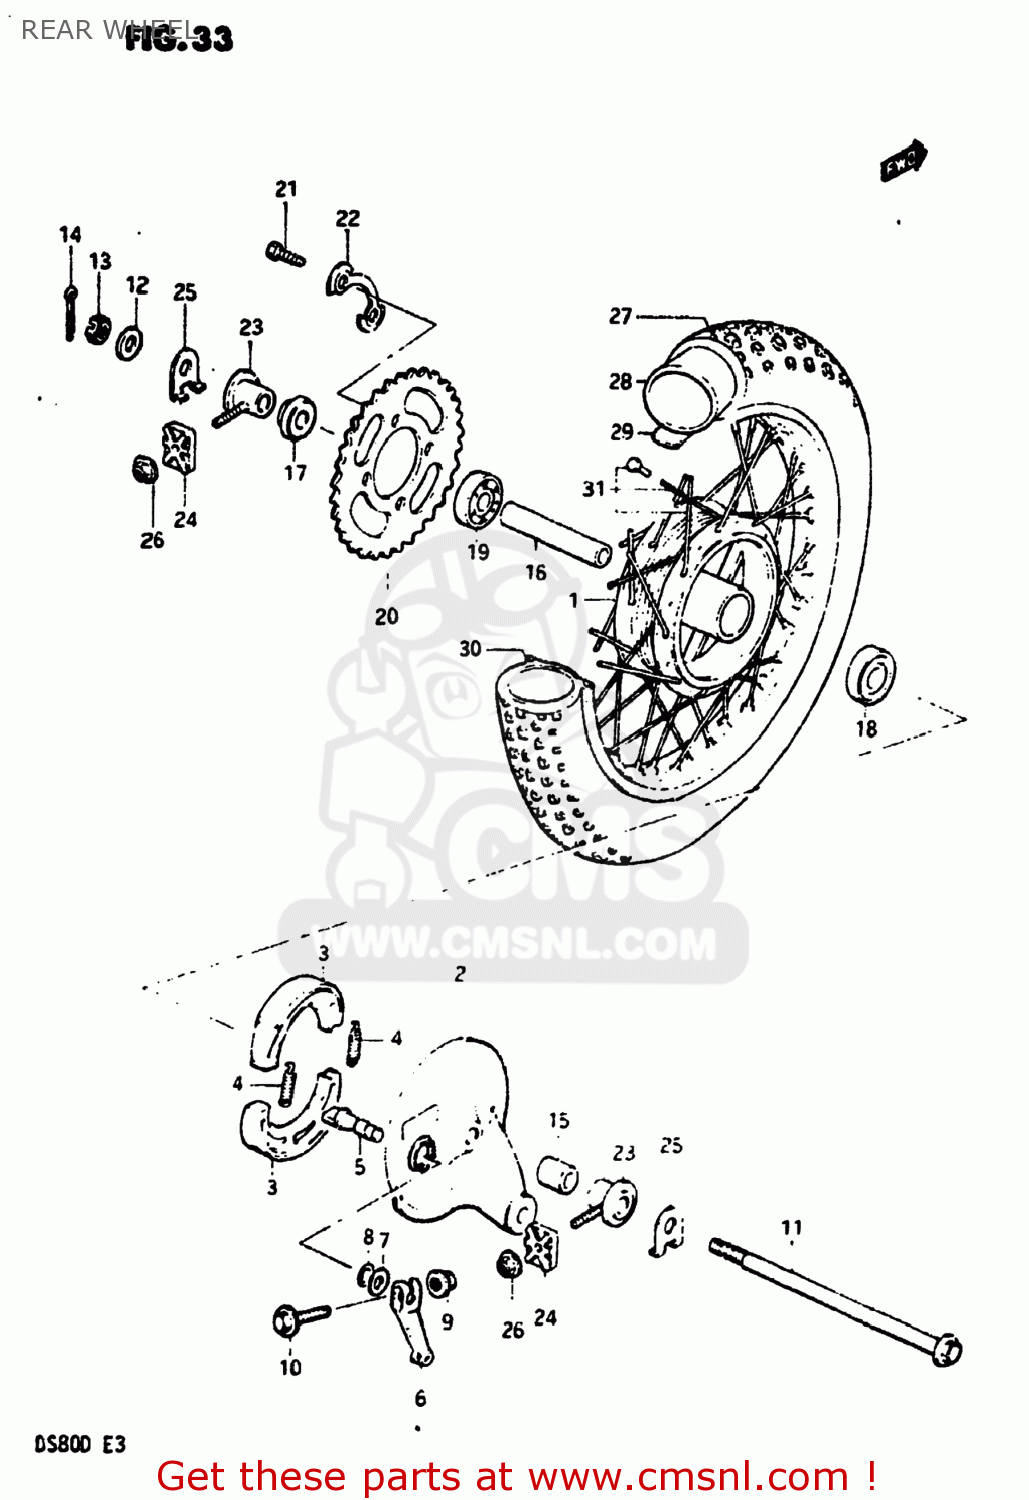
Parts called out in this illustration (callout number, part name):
1	HUB,RR
2	PANEL,REAR BRAKE ANCHOR
3	SHOE,BRAKE (MCA)
4	SPRING(L:34)
5	CAM,FRONT BRAKE
6	LEVER,RR BRAKE CAM
7	WASHER (14.5X22X1.6)
8	O-RING (D:2.4 ID:13.8)
9	NUT
10	BOLT 6X35
11	AXLE,REAR
12	WASHER
13	NUT, REAR AXLE
14	COTTER PIN
15	SPACER(12.1X22X22)
16	SPACER(12.6X19X91)
17	SPACER,RR AXLE,L
18	BEARING
19	BEARING
20	SPROCKET,REAR
21	BOLT(8X25)
22	WASHER
23	ADJUSTER,CHAIN
24	PLATE,CHAIN ADJUSTER GEAR
25	WASHER,CHAIN ADJUSTER
26	NUT
27	TIRE(3.00 12)
28	TUBE,INNER
29	PROTECTOR,INNER TUBE
30	RIM,RR WHEEL(1.60X12)
31	SPOKE SET,REAR WHEEL
